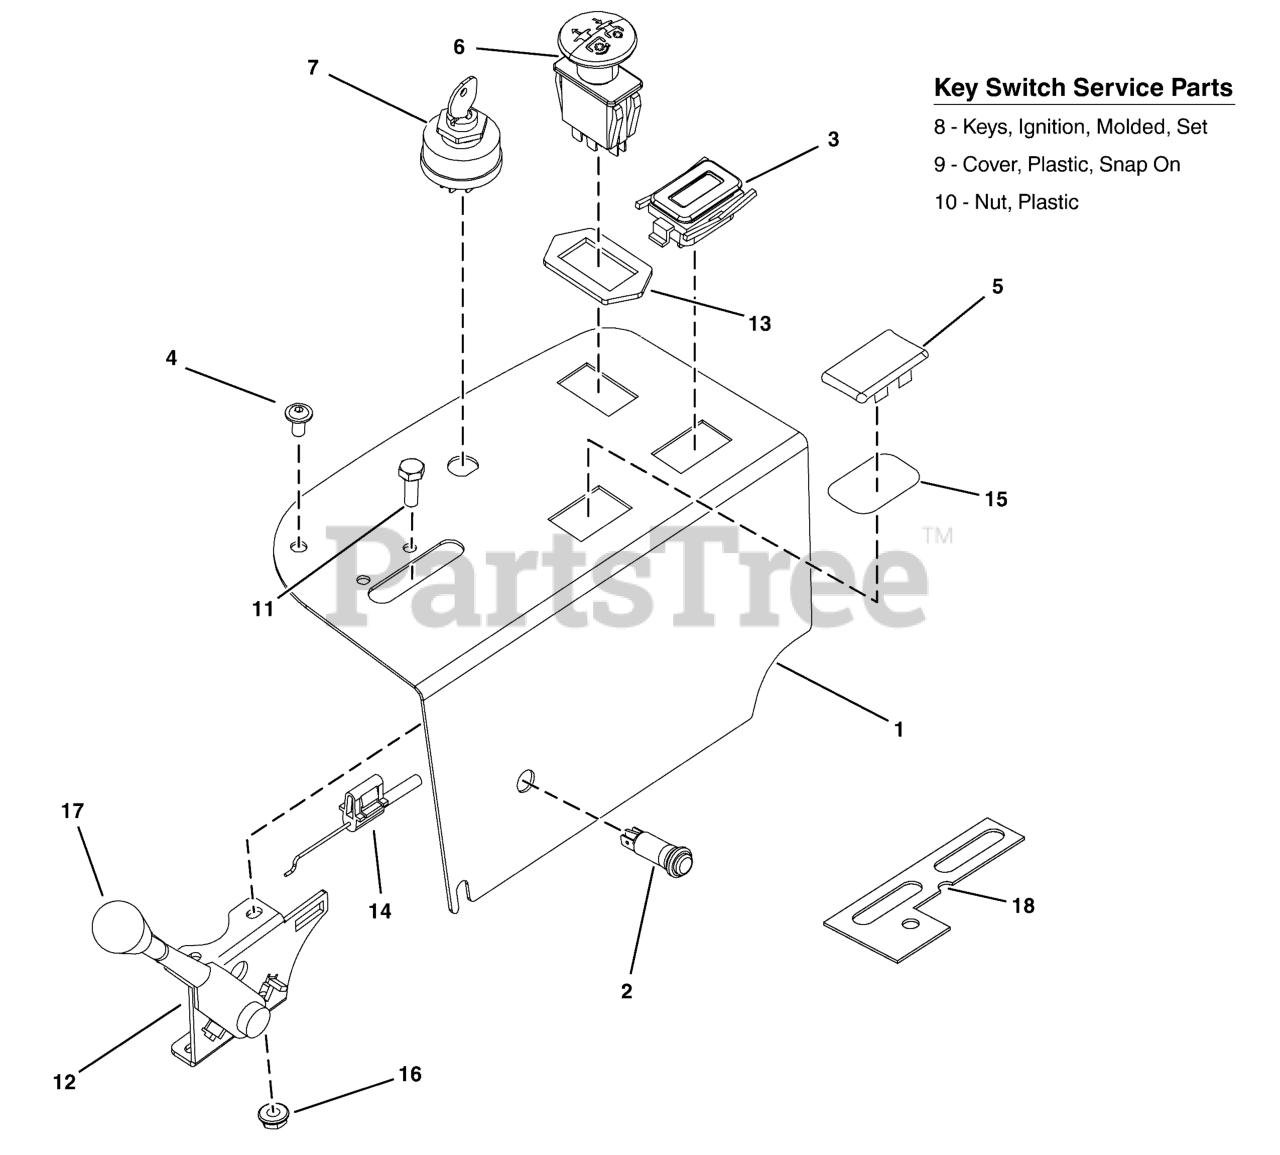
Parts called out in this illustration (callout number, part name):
1	PANEL, CONTROL, IS2100/3200 - BLK
2	LIGHT, INDICATOR, PANEL, LED, RED
3	HOURMETER
4	SCREW, FLANGE, ALLEN HD, 1/4-20X.5 S/S
5	PLUG, .820X1.44 HOLE, BLACK PLASTIC
6	SWITCH-PTO PUSH
7	SWITCH, IGNITION, 6 POST
8	KEY, IGNITION MOLDED SET
9	COVER, PLASTIC, SNAP ON
10	PLASTIC NUT
11	SCREW, #10-24 X 3/4" ROUND PHILLIPS
12	LEVER, THROTTLE CONTROL, HEAVY-DUTY
13	RING, SWITCH RETAINER
14	CABLE, THROTTLE, 42"
15	O-RING, 7/8" ID X 1/16" W
16	NUT, Hex, Nylon Lock, #10-24
17	THROTTLE CONTROL HANDLE/KNOB
